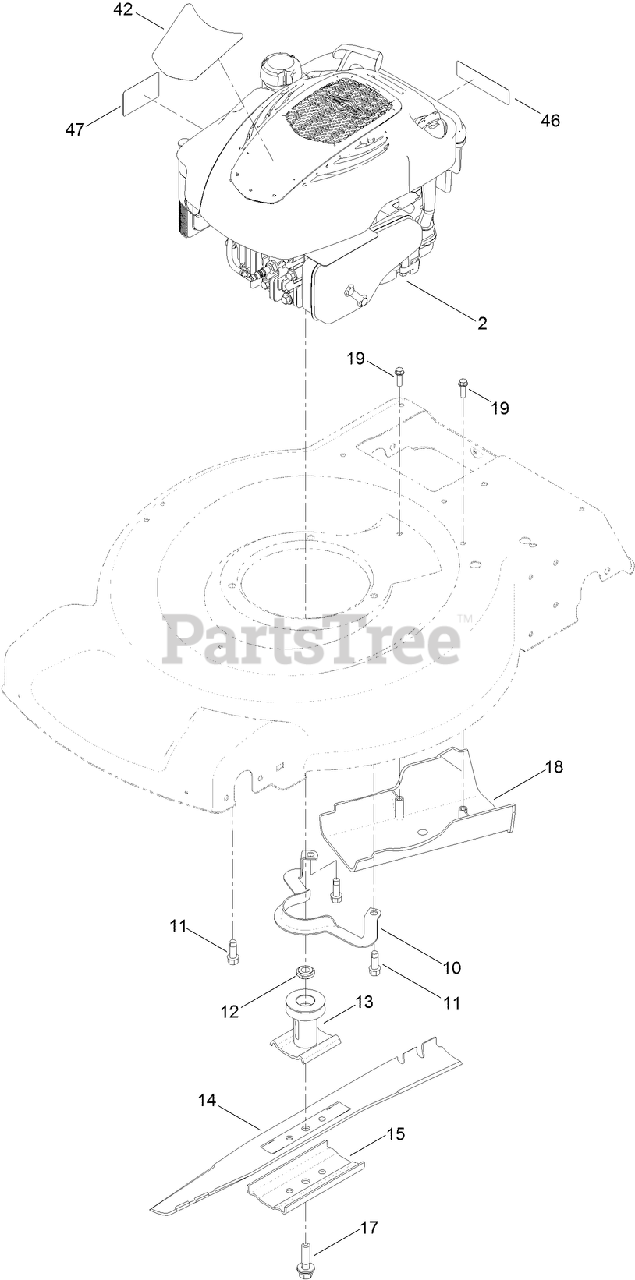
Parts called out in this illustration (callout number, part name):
10	GUIDE-BELT
11	SCREW-TAPTITE
12	SPACER-DRIVER
13	DRIVER-BLADE
14	BLADE-22 INCH
15	SUPPORT-BLADE
17	BOLT-BLADE
18	COVER-BELT
19	SCREW-HWH
42	DECAL-SHROUD
46	DECAL-ARRESTER, SPARK
47	DECAL-FUEL LEVEL
